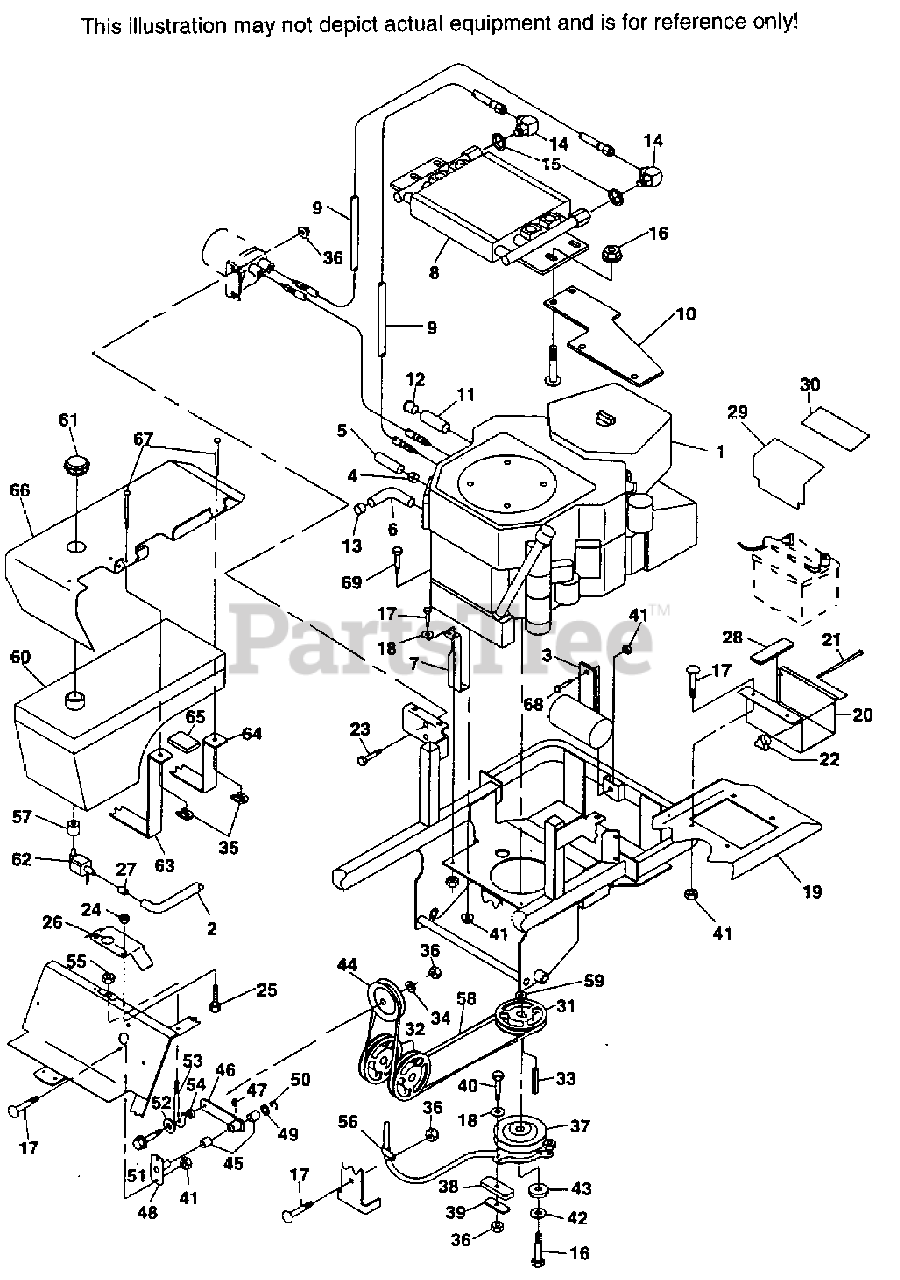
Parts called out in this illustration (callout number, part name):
19	FENDER, LH
20	BATTERY BOX
22	WING NUT, 1/4-20
24	NUT, 1/4-20 SERRATED FLANGE HEX HEAD
26	BELT GUARD
27	FUEL HOSE CLAMP
28	RUBBER PAD
29	BATTERY COVER
30	BATTERY COVER PAD
31	PULLEY
32	PUMP PULLEY
33	KEY, 1/4 X 1/4 X 1-1/2"
34	FLATWASHER, 3/8" SPECIAL
35	U-NUT, 1/4-20
36	ELASTIC STOP NUT, 5/16-18
37	ELECTRIC CLUTCH
38	RUBBER PAD, CLUTCH STOP
39	BACKING PLATE
41	NUT, 5/16-18 SERRATED FLANGE HEX HEAD
43	FLATWASHER, 7/16" SPECIAL
44	IDLER PULLEY
45	BUSHING
46	IDLER ARM(INCLUDES BUSHINGS AND GREASE
47	GREASE FITTING
48	IDLER PIVOT BASE
49	FLATWASHER, 3/4"
49A	FLATWASHER, 3/4" SPECIAL
50	RETAINING RING, 3/4" EXTERNAL "E"
52	FLATWASHER 3/8 X 1-1/2 X .06
53	"J" BOLT
54	SPACER
57	BUSHING, FUEL TANK VALVE
58	BELT, PUMP DRIVE
59	SPACER, CRANKSHAFT
60	FUEL TANK(INCLUDES SHUT-OFF VALVE)
61	FUEL TANK CAP
62	FUEL SHUT-OFF VALVE
63	FUEL TANK STRAP, LONG
64	FUEL TANK STRAP, SHORT
65	RUBBER PAD
66	FENDER ASSEMBLY, RH(WITH DECAL)
68	CAPSCREW, 5/16-18 X 3/4" SERRATED FLANGE HEX
69	CAPSCREW, 5/16-18 X 1-1/2"
